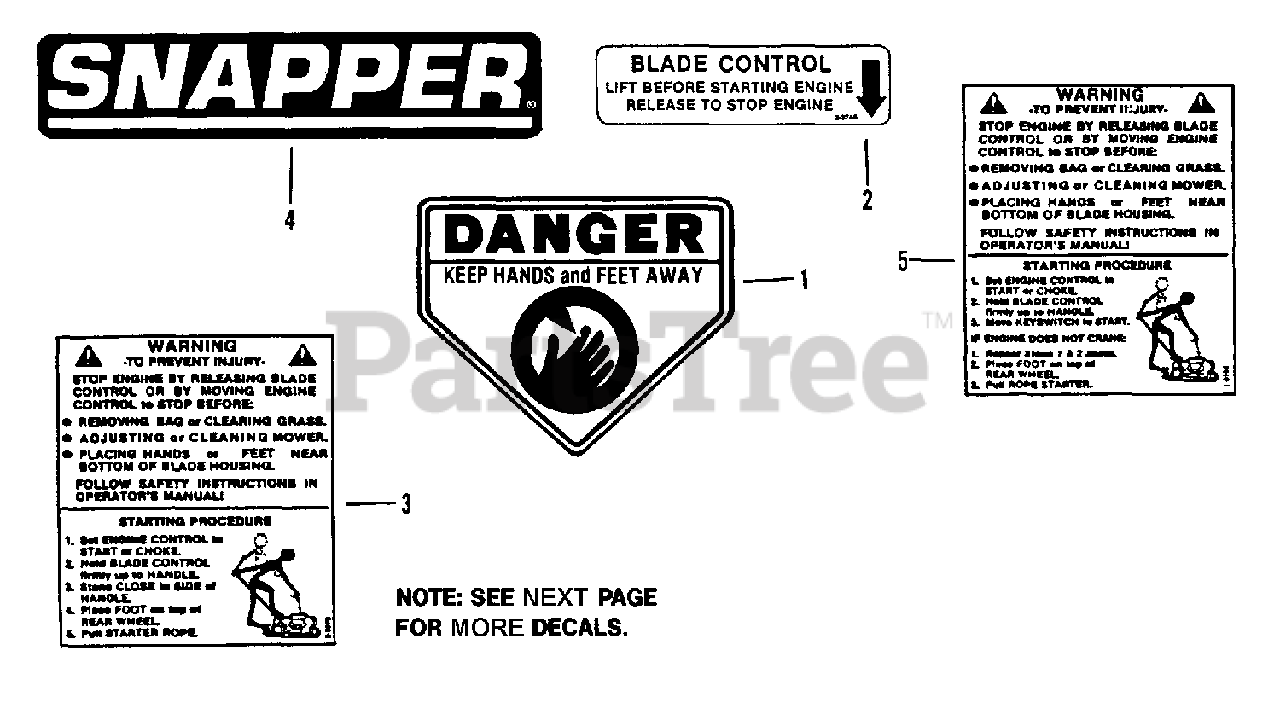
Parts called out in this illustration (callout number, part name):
1	DECAL, Danger
2	DECAL, Blade Control
3	DECAL, Warning
4	DECAL, SNAPPER
5	DECAL, Warning & Starting
